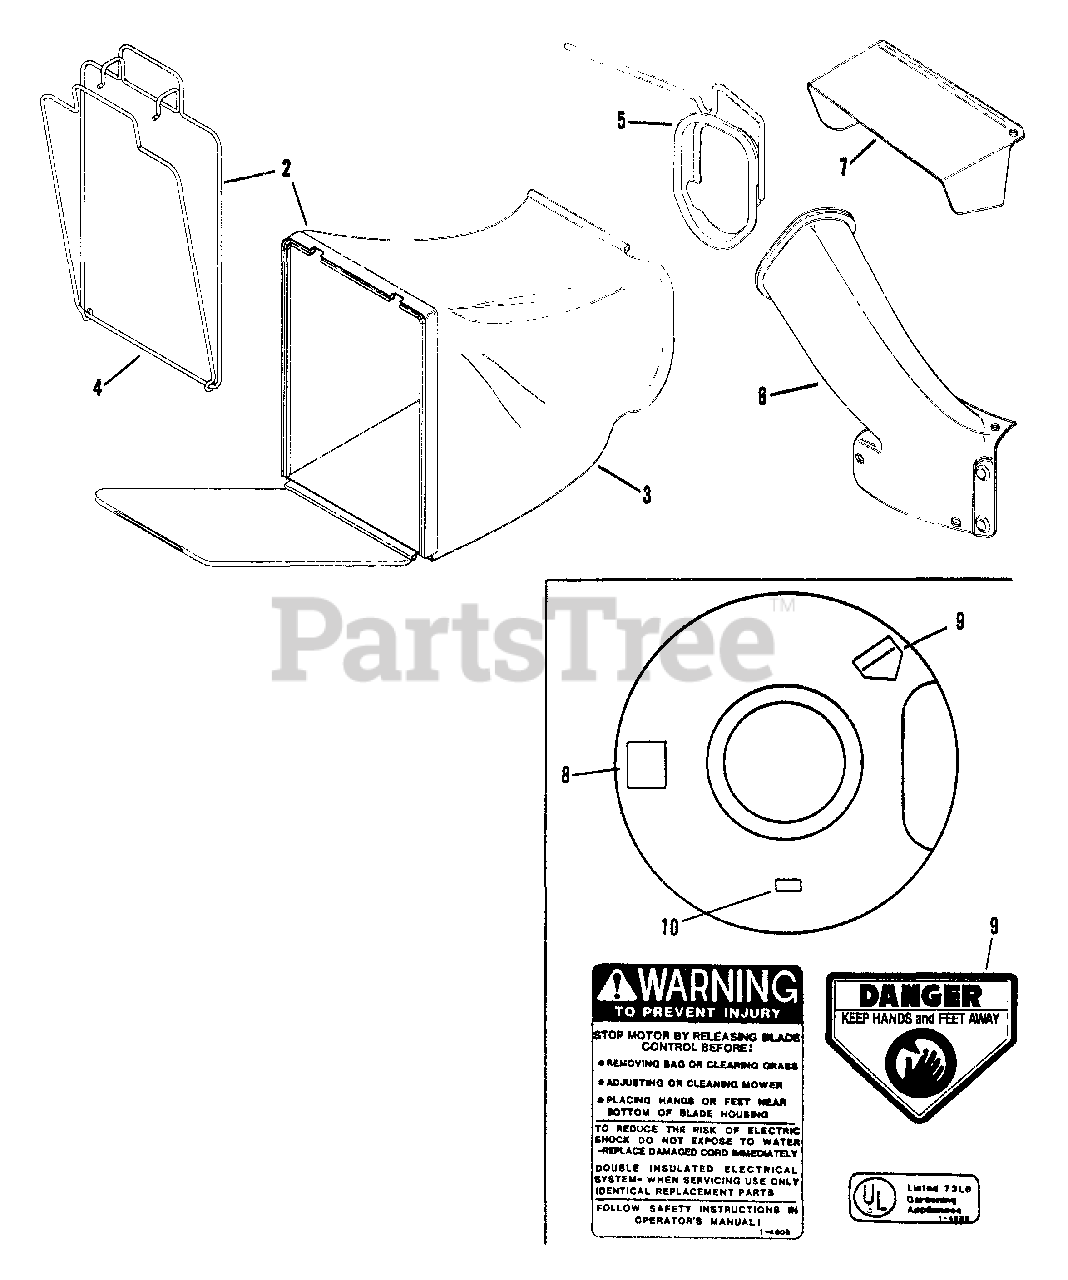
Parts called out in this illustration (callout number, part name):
1	KIT, KWIK-N-EZY
2	ASSEMBLY, Grass Bag
3	BAG, KWIK-N-EZY
4	ASSEMBLY, Bag Wire
5	CONNECTOR, Grass Bag
6	ADAPTER, Grass Bag
7	CHUTE, Side
8	DECAL, Warning
9	DECAL, CPSC Warning
10	DECAL, UL Listing
